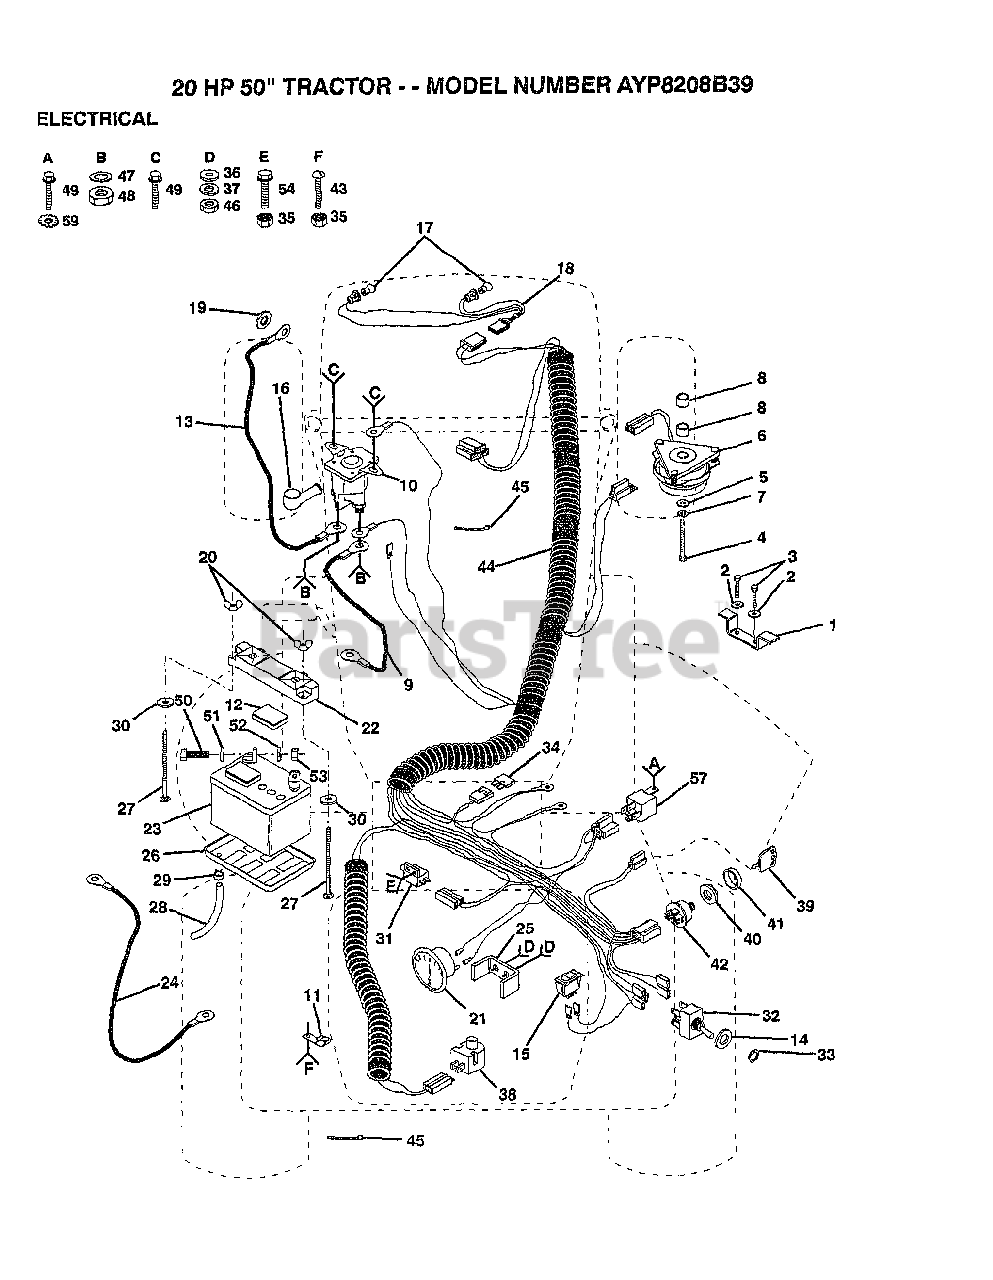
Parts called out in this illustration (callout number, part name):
2	LOCKWASHER
3	BOLT
5	WASHER
7	LOCKWASHER
8	SPACER-CLUTCH
9	CABLE-BATTERY T
12	"CAP,BATTERY "
13	"CABLE,STARTER T"
14	WASHER
15	SWITCH LT
17	HEADLAMP BULB
18	"HARNESS,LIGHT SOC"
19	LOCKWASHER
21	AMMETER T
24	CABLE T
26	"TRAY T, BATTERY"
27	BOLT
28	"DRAIN TU T, BATT"
29	HOSE CLAMP T
30	WASHER
31	SWITCH-INTER. GT
33	HEX NUT T
34	FUSE HYT
35	"NUT,KEPS"
36	WASHER
38	SWITCH SEAT
39	KEY
40	NUT IGNITION
44	HARNESS
45	WIRE TIE
48	NUT
49	SCREW
50	BOLT LT
51	WASHER
52	LOCKWASHER
54	SCREW
57	RELAY ASSY T
59	LOCKWASHER
